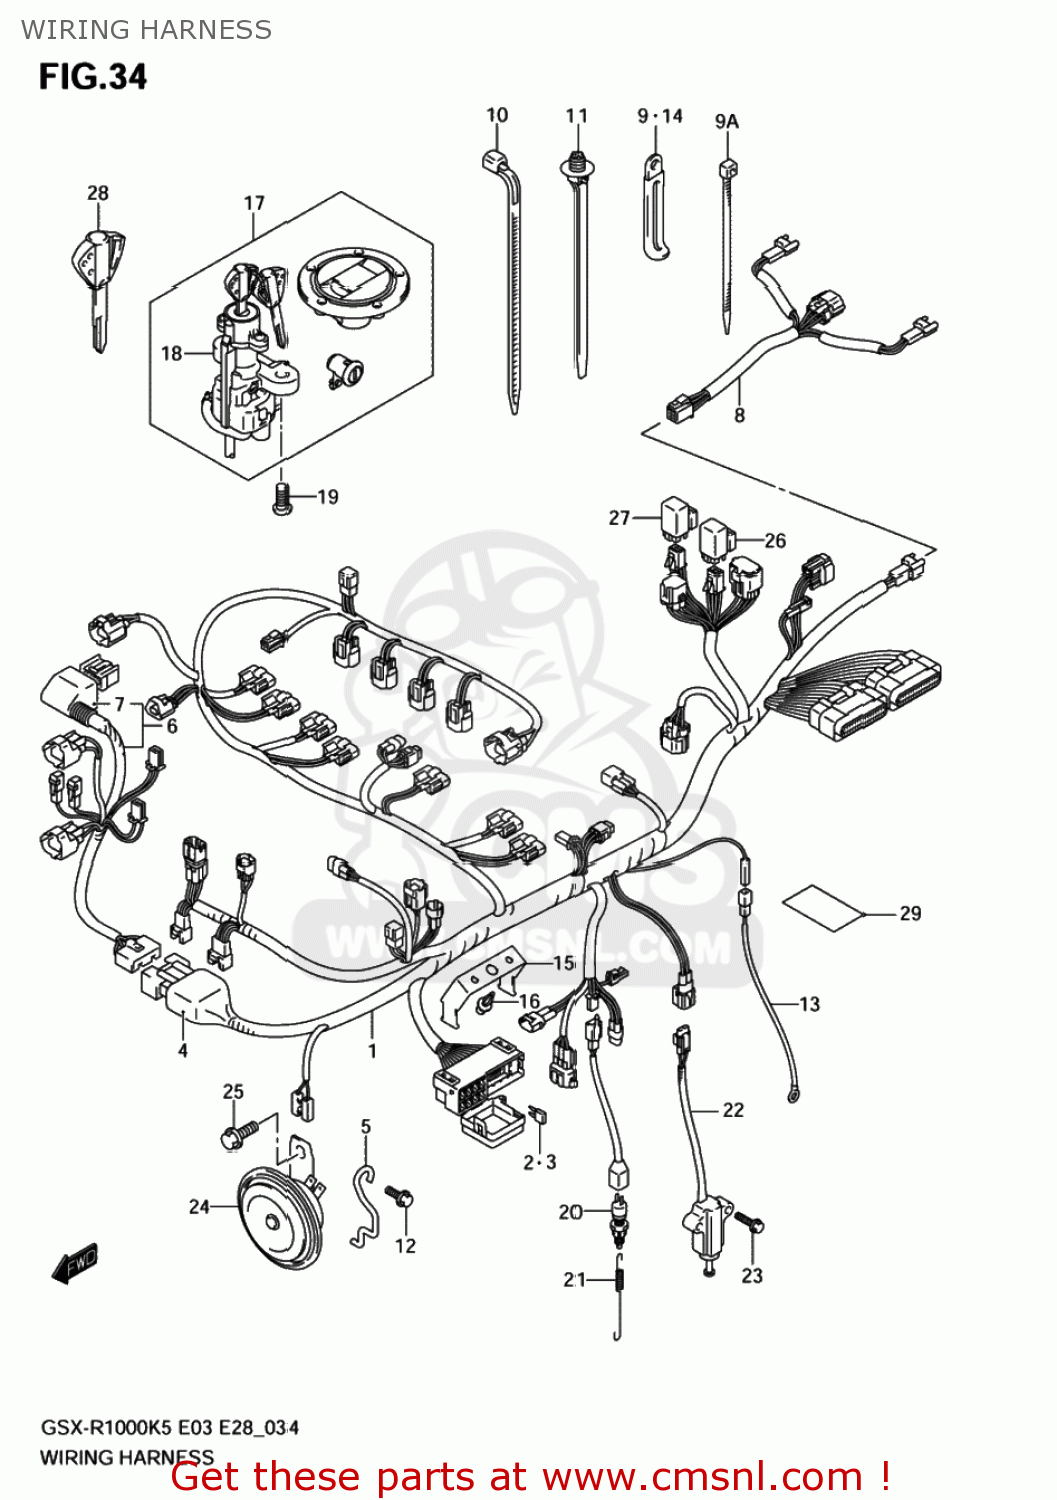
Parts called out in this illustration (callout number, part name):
1	HARNESS,WIRING NO.1
2	FUSE(10A)
3	FUSE(15A)
4	COVER,CONNECTOR
5	GUIDE,WIRING HARNESS
6	HARNESS,WIRING NO.2
7	COVER,CONNECTOR
8	WIRE,RR COMB
9	CLAMP(L:45)
9A	CLAMP(L:100)
10	CLAMP(L:125)
11	CLAMP(L:154)
12	BOLT
13	WIRE,OIL PRESSURE SWITCH LEAD
14	CLAMP(L:45)
15	BRACKET,FUSE
16	CLIP(BLACK)
17	LOCK SET
18	LOCK ASSY,STEE
19	BOLT(8X20)
20	SWITCH ASSY,STOP LAMP
21	SPRING
22	SWITCH ASSY,SIDE STAND
23	BOLT
24	HORN ASSY,HIGH
25	BOLT
26	RELAY ASSY
27	RELAY ASSY
28	KEY,BLANK
29	TAPE,WIRING HARNESS(28X50X0.13
